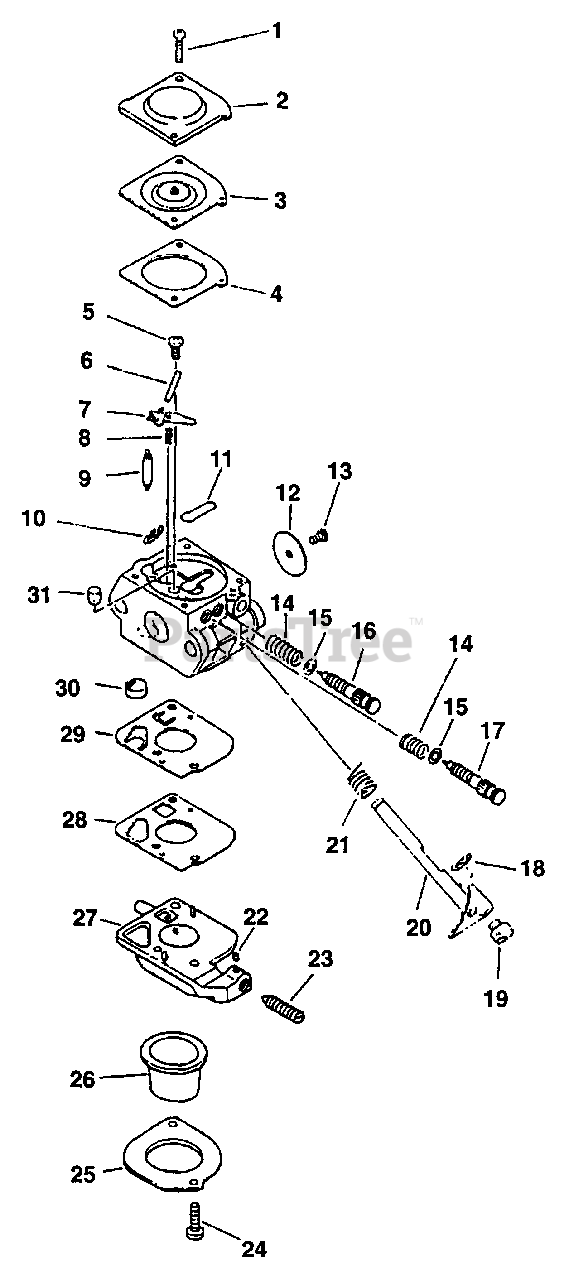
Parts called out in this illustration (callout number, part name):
2	COVER, METERING
3	DIAPHRAGM
4	GASKET, METERING
5	SCREW, METERING LEVER PIN
6	PIN
7	LEVER, METERING
8	SPRING
9	VALVE, NEEDLE
10	RING, RETAINING
11	PLUG, WELCH
12	VALVE, THROTTLE
16	NEEDLE - LOW SPEED
17	NEEDLE - HIGH SPEED
18	RING, RETAINING
20	SHAFT, THROTTLE
21	SPRING, RETURN
22	PIECE, FRICTION
23	SCREW, IDLE ADJUST
24	SCREW, RETAINER
25	RETAINER, PURGE BULB
26	BULB, PURGE
27	BASE, PURGE
28	GASKET, PURGE
29	DIAPHRAGM, PURGE
30	STRAINER
31	NOZZLE, CHECK VALVE
